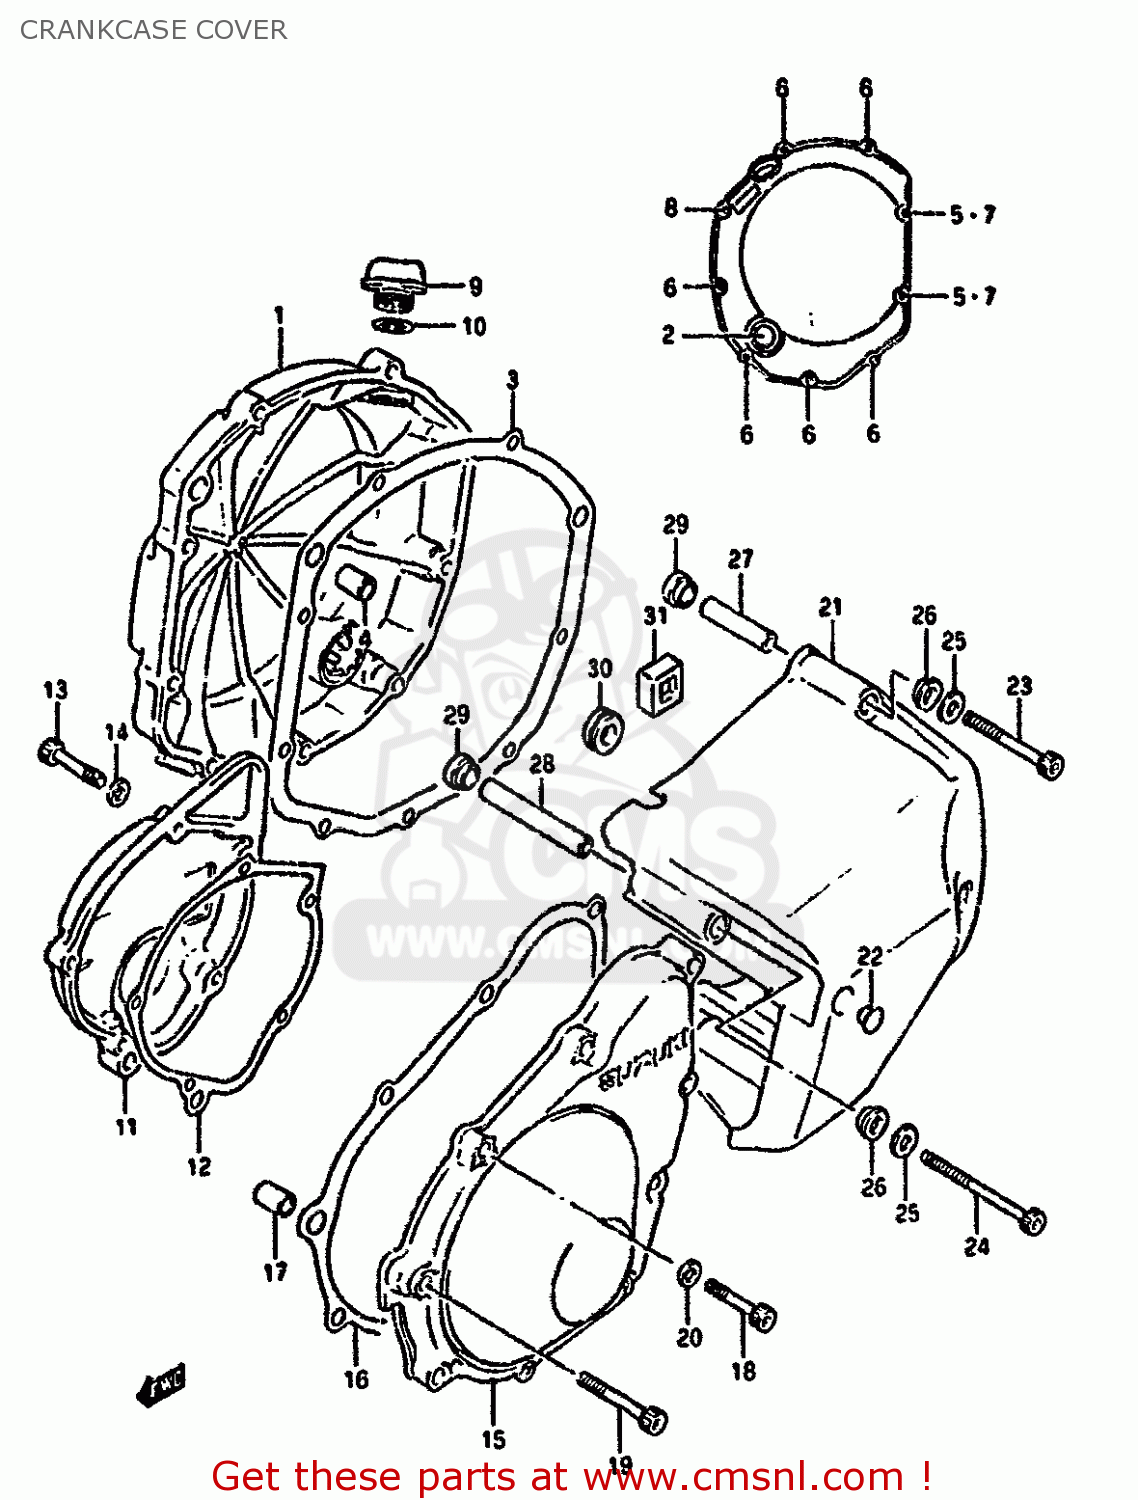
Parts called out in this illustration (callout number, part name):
1	COVER,CLUTCH
2	LENS,OIL LEVEL CHECK
3	GASKET,CL COVER (NAS)
4	PIN
5	GASKET(5.8X11X1.2) (NAS)
6	BOLT
7	BOLT
8	BOLT
9	PLUG
10	O RING(D:3.1,ID:16.8)
11	COVER,SIGNAL GENERATOR
12	GASKET,SIGNAL GENERATOR COVER (NAS)
13	BOLT
14	GASKET(5.8X11X1.2) (NAS)
15	COVER,STARTER GEAR
16	GASKET,STARTER GEAR COVER (NAS)
17	PIN (11X20)(SUS)
18	BOLT
19	BOLT
20	GASKET(5.8X11X1.2) (NAS)
21	COVER,SPROCKET
22	CAP(OD:12)
23	BOLT
24	BOLT
25	WASHER
26	WASHER(8.7X15X2.1)
27	SPACER (L=45.9)
28	SPACER(6.1X9X55.9)
29	WASHER(8.7X16X5)
30	CUSHION
31	DAMPER,SECONDARY COVER
